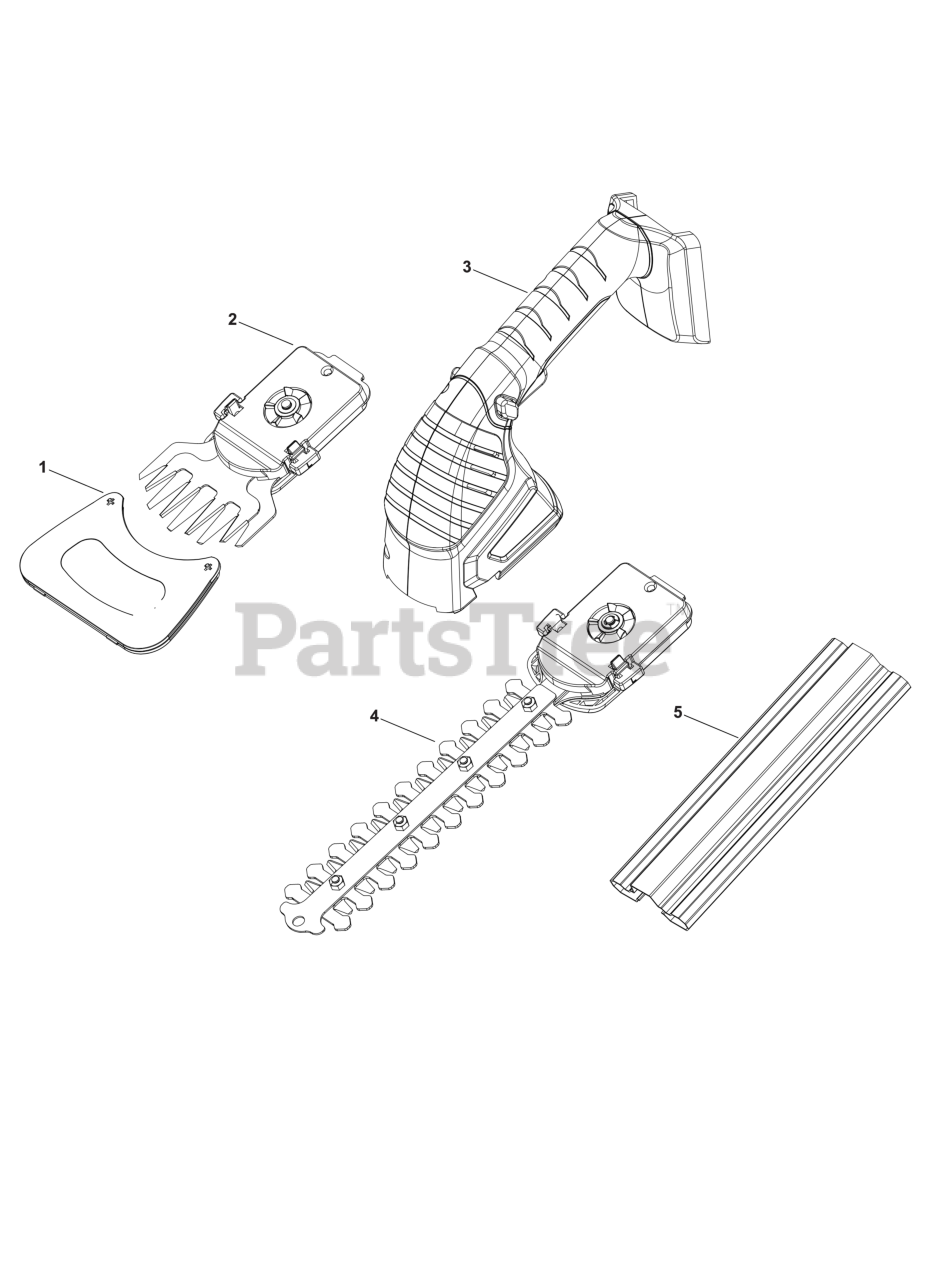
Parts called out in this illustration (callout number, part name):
1	SHEAR BLADE COVER
2	SHEAR BLADE ASSEMBLY
3	MAIN BODY ASSEMBLY
4	TRIMMER BLADE ASSEMBLY
5	TRIMMER BLADE COVER
